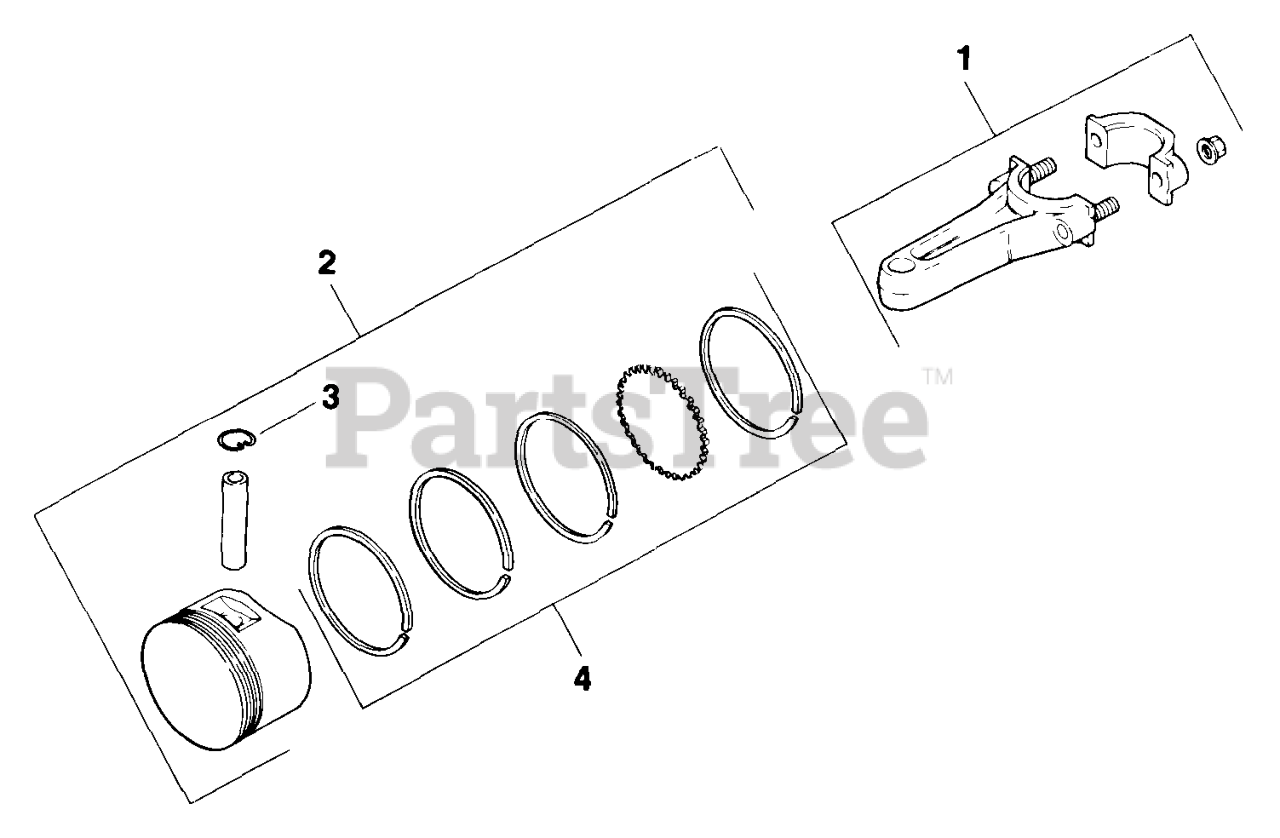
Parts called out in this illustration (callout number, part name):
1	Connecting Rod (Std.)
1	Connecting Rod (.010)
2	Piston W/Ring Set (Std.)
2	Piston W/Ring Set (.003)
2	Piston W/Ring Set (.010)
2	Piston W/Ring Set (.020)
2	Piston W/Ring Set (.030)
3	Retainer, Piston Pin
4	Ring Set (Std. & .003)
4	Ring Set (.010)
4	Ring Set (.020)
4	Ring Set (.030)
